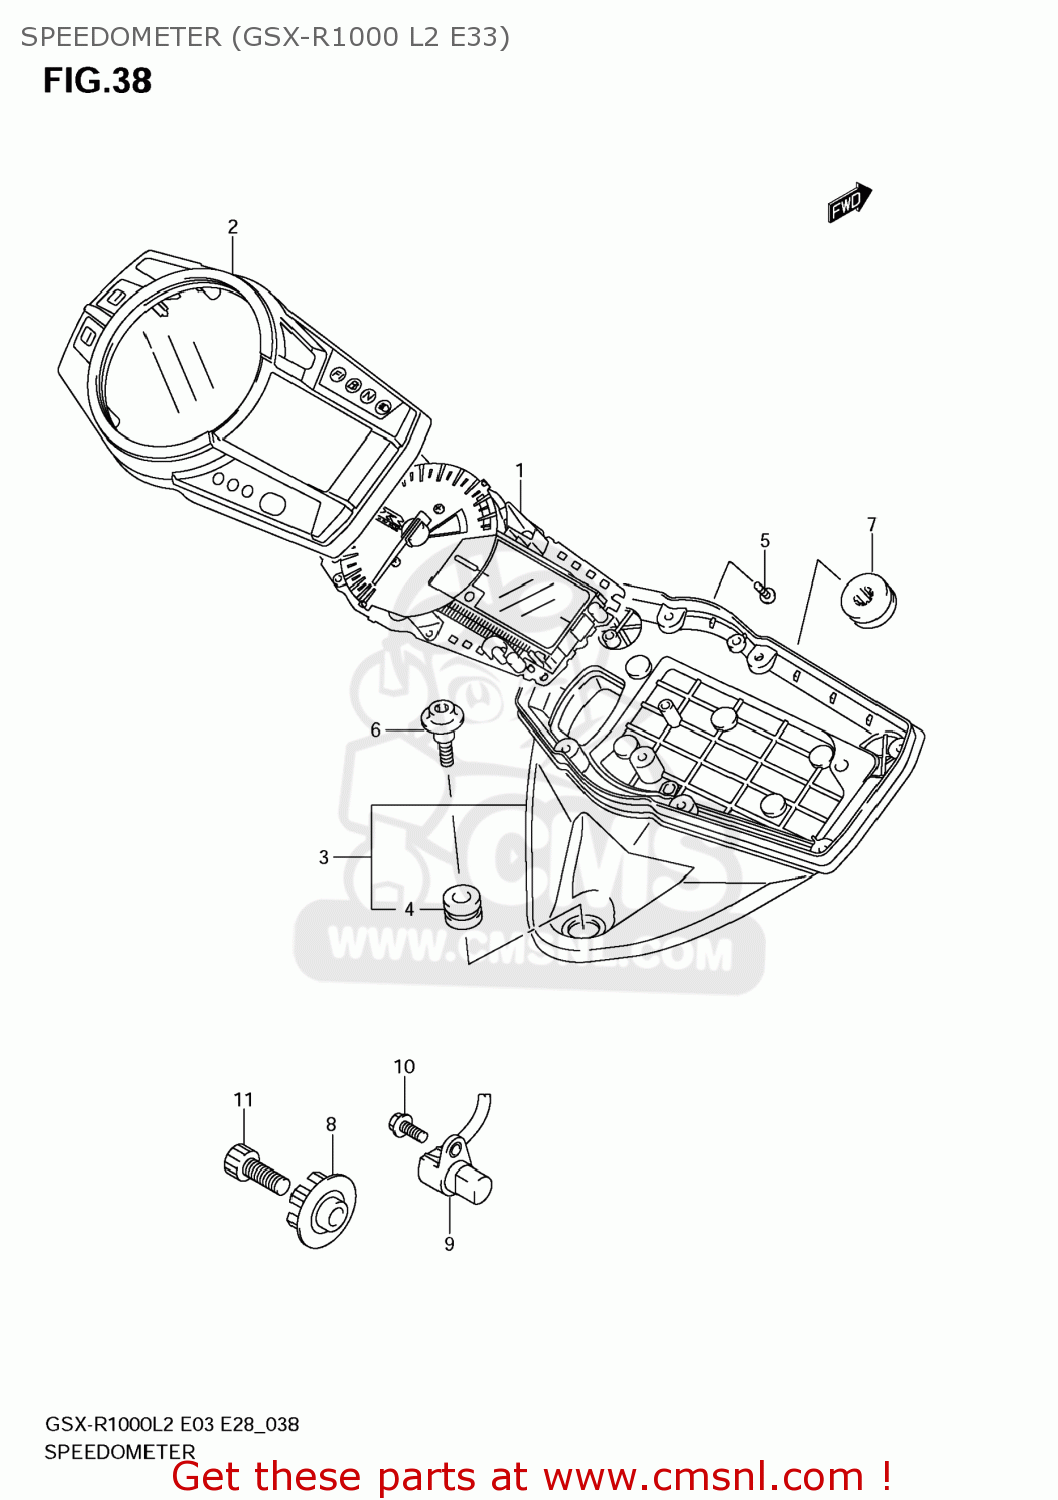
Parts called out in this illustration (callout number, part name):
1	COMBINATION METER
2	CASE ASSY,UPR
3	CASE ASSY,LWR
4	CUSHION,METER
5	SCREW(3X16)
6	SCREW,SPEEDOMETER
7	CUSHION
8	ROTOR,SPEED
9	SENSOR,SPEED
10	BOLT
11	BOLT
